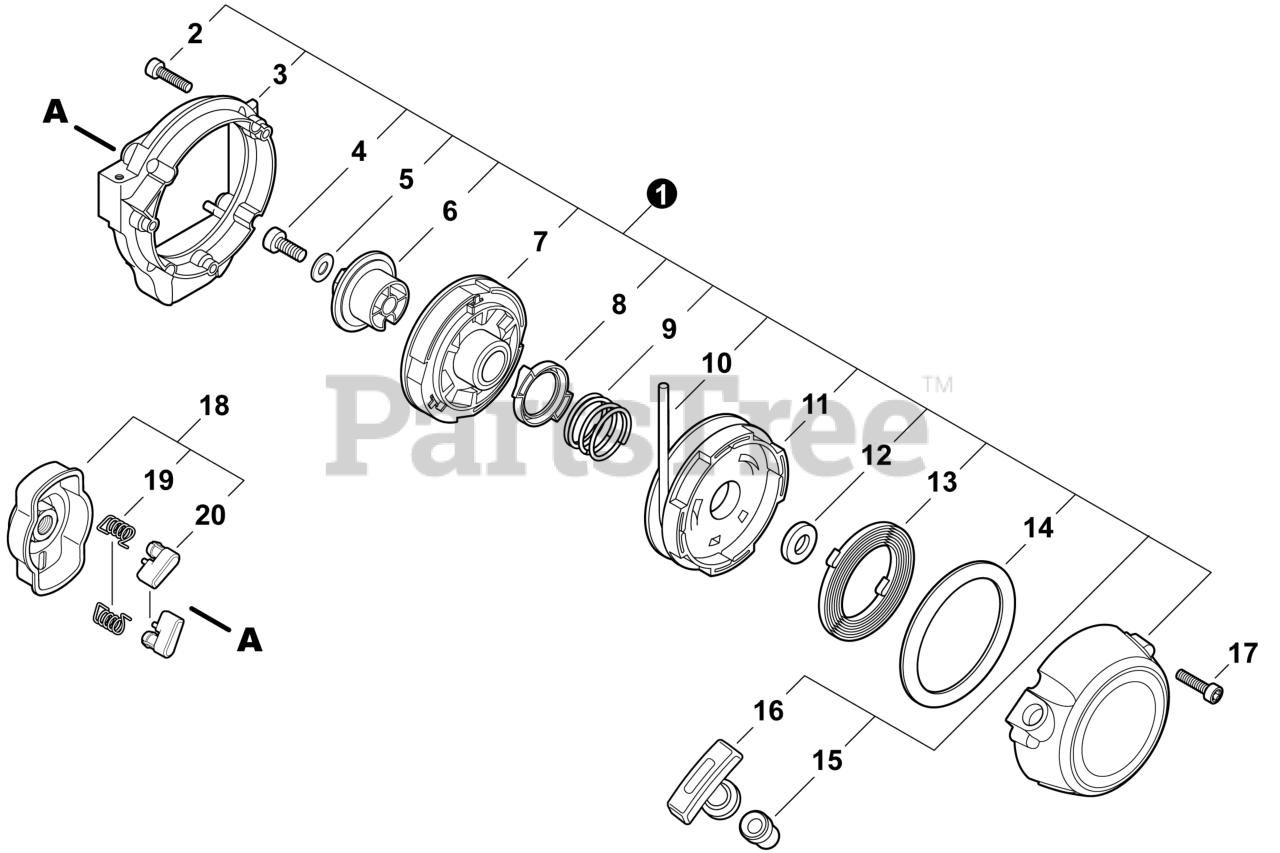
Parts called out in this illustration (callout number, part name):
1	STARTER ASSY, RECOIL
2	BOLT, TORX 4x16
3	BRACKET, STARTER
4	BOLT, TORX 5x12
5	WASHER 5.5x12x0.8
7	CLUTCH ASSY
10	ROPE, STARTER 3x900
12	COLLAR 8
13	SPRING, RECOIL
14	PLATE, STARTER
15	GUIDE, ROPE
16	GRIP, STARTER
17	BOLT, TORX 4x16
18	PAWL ASSY, STARTER
19	SPRING, RETURN
20	PAWL, STARTER - BLACK
